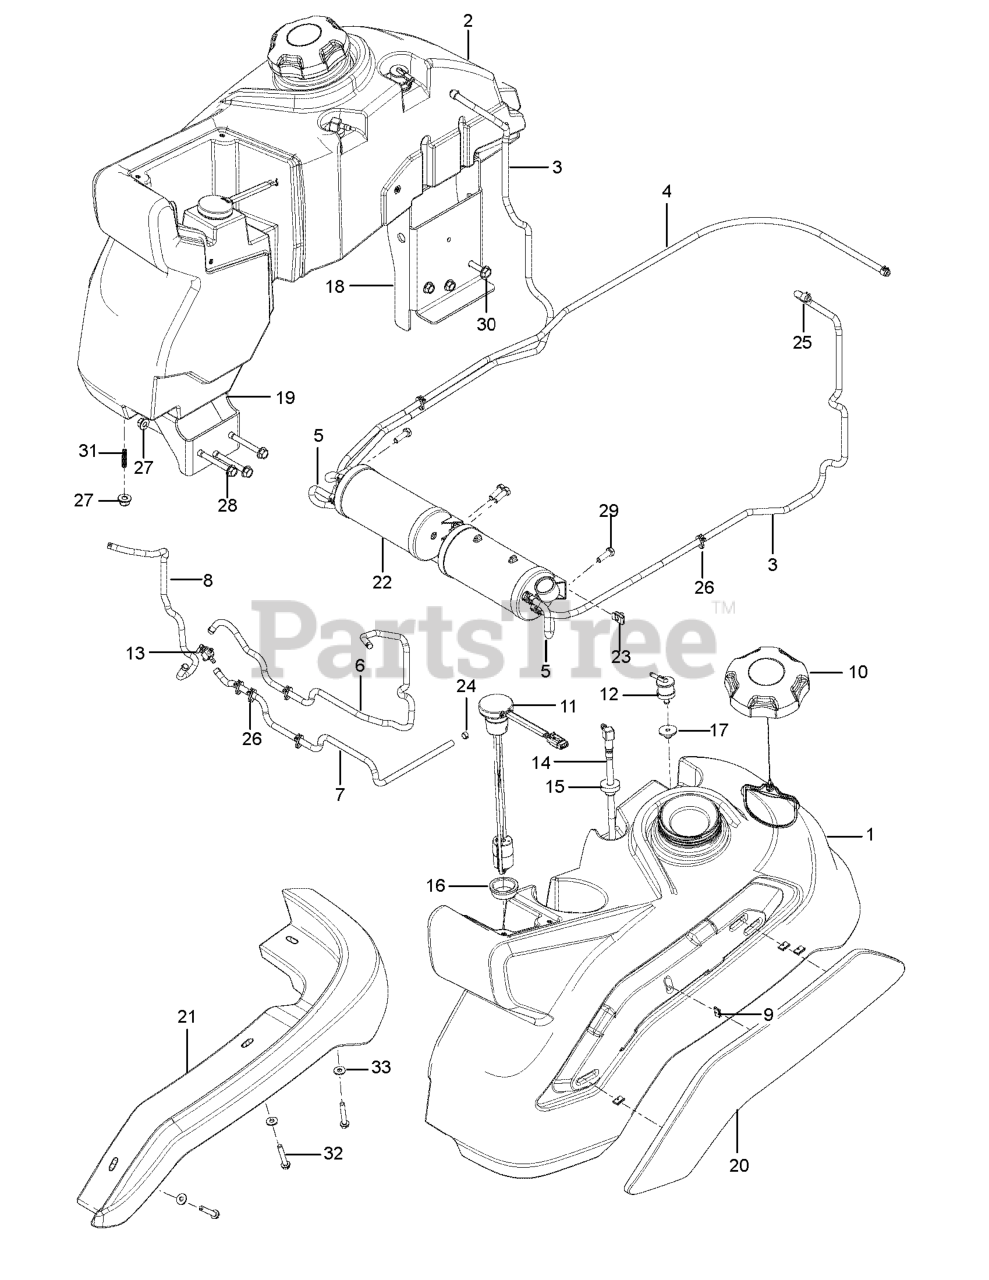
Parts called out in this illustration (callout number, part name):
1	TANK UNIT ASSY LH 2018 PROD. Y
2	TANK UNIT ASSY RH 2018 PROD. Y
3	HOSE.3/16".VAPOR.LINE.38"LGTH
5	HOSE 3/16" VAPOR LINE 13" LENG
6	HOSE 1/4" LOW PERMEATION FUEL
8	HOSE.1/4".LOW.PERM.FUEL.LN.24"
9	CLIP.U-TYPE
10	CAP, FUEL
11	SENSOR.FUEL.LVL.FLOAT.V500
12	VALVE.FUEL.CHECK
13	FUEL VALVE
14	TUBE.ASM.FUEL.TANK.PICK-UP.LH
15	BUSHING OUTLET T
16	GROMMET, FUEL SENSOR
17	GROMMET.CHECK.FUEL
18	BRACKET.FUEL.TANK.REAR.SUP.431
19	BRACKET.FUEL.TANK.REAR.SUP.431
20	COVER.LH.FUEL.TANK/CONSOLE APP
21	GUARD.MUD.LH
22	CANISTER.FLEX.6.3GAL3/16".TANK
23	1/4-20 U NUT
24	HOSE CLAMP
25	CLAMP, HOSE
26	CABLE.TIE.6".FIRTREE.PZ.REFRES
27	5/16-18 NYLOC FLANGE NUT
28	BOLT HEX FLGHD 5/16-18X3 GR. 5
29	BOLT
30	SCREW
31	SCREW.5/16-18X1.25"THREADED
32	SCREW.1/4-20X1.5IN.HEX.MACH
33	WASHER
34	HOSE.1/4".LOW.PERM.FUEL.LN.3"
35	TIE, PLASTIC
